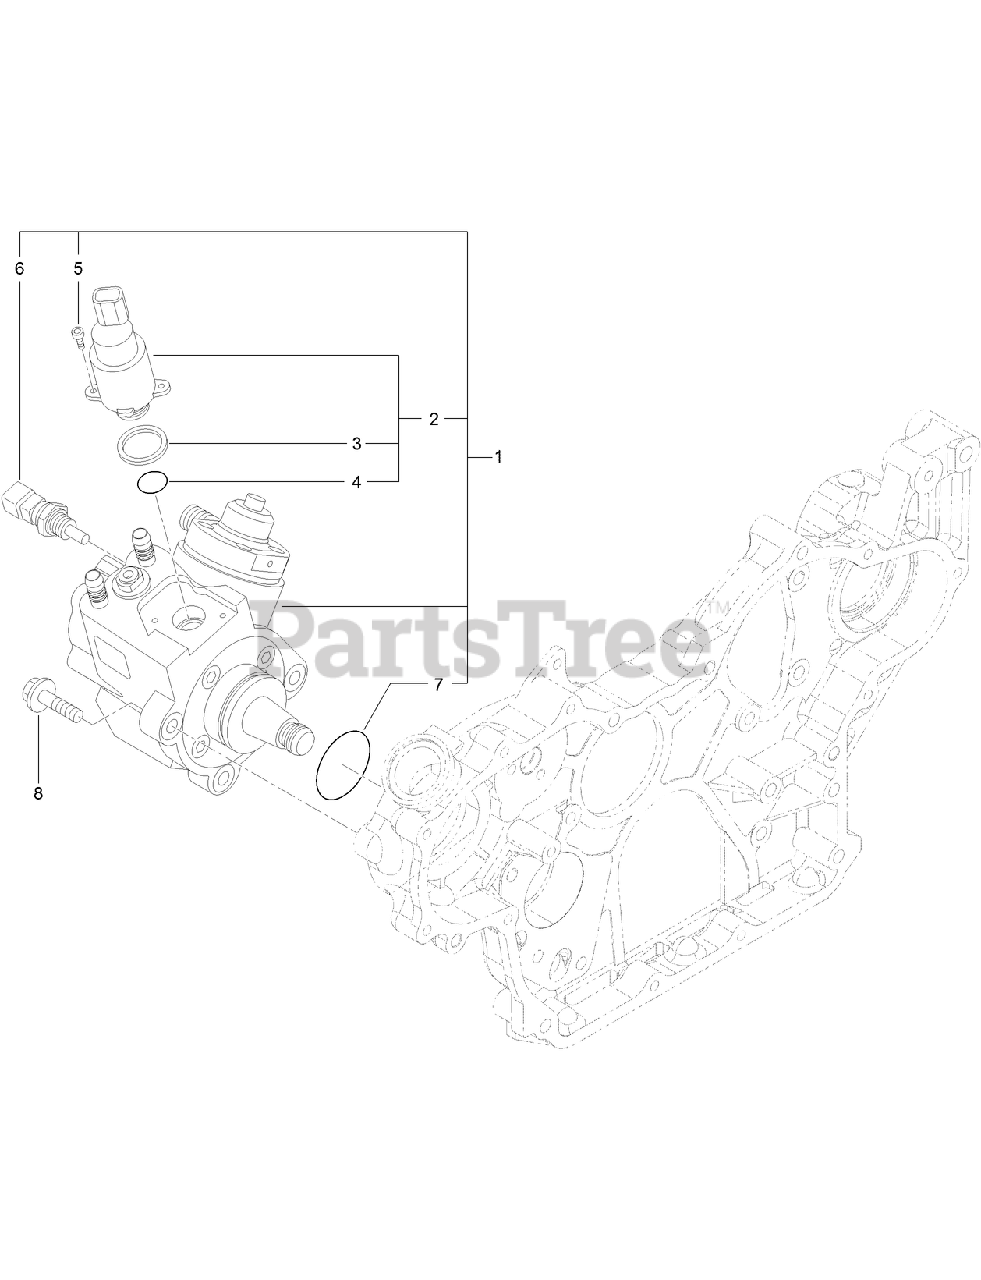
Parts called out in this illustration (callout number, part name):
1	FUEL PUMP ASM
2	VALVE ASM
3	RING-SEALING
4	O-RING
6	SENSOR-TEMPERATURE
7	O-RING
